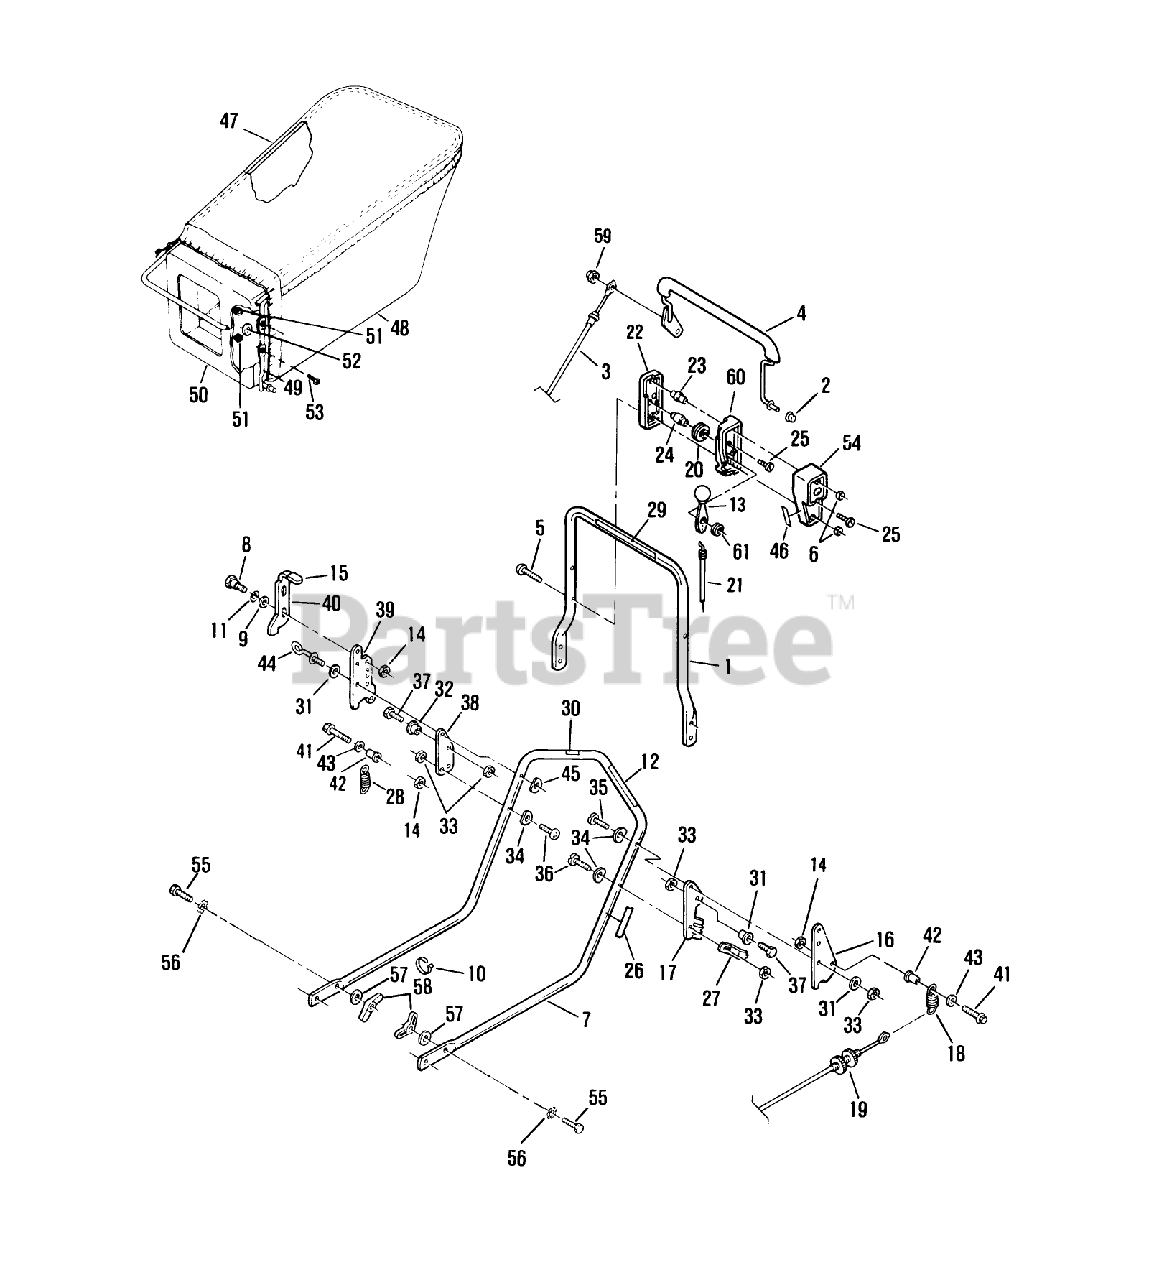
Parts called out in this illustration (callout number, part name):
3	CONTROL CABLE
4	CONTROL LEVER ARG
5	SCREW
6	NUT C/LOCK E
7	HANDLE SECTION
8	BOLT RB&W
9	WASHER M
13	LEVER&KNOB AY WES
14	LOCKNUT E
15	KNOB (S&R)
18	SPRING
19	CABLE AY
20	PULLEY PL
21	T/CABLE WESCON
22	OUTER CONTROL CASE
23	COLUMN
24	PIN SKF
25	SCREW
33	NUT-LOCK F
34	WASHER-CURVED
35	SCREW LARSON
42	SPACER ROCKFORD
43	WASHER
47	HANGER BAG TROX
50	BAG ADAPTOR PL
51	LOCKNUT E
52	WASHER
57	WASHER
58	NUT-WING
59	NUT ACORN
61	WASHER-SPRING
